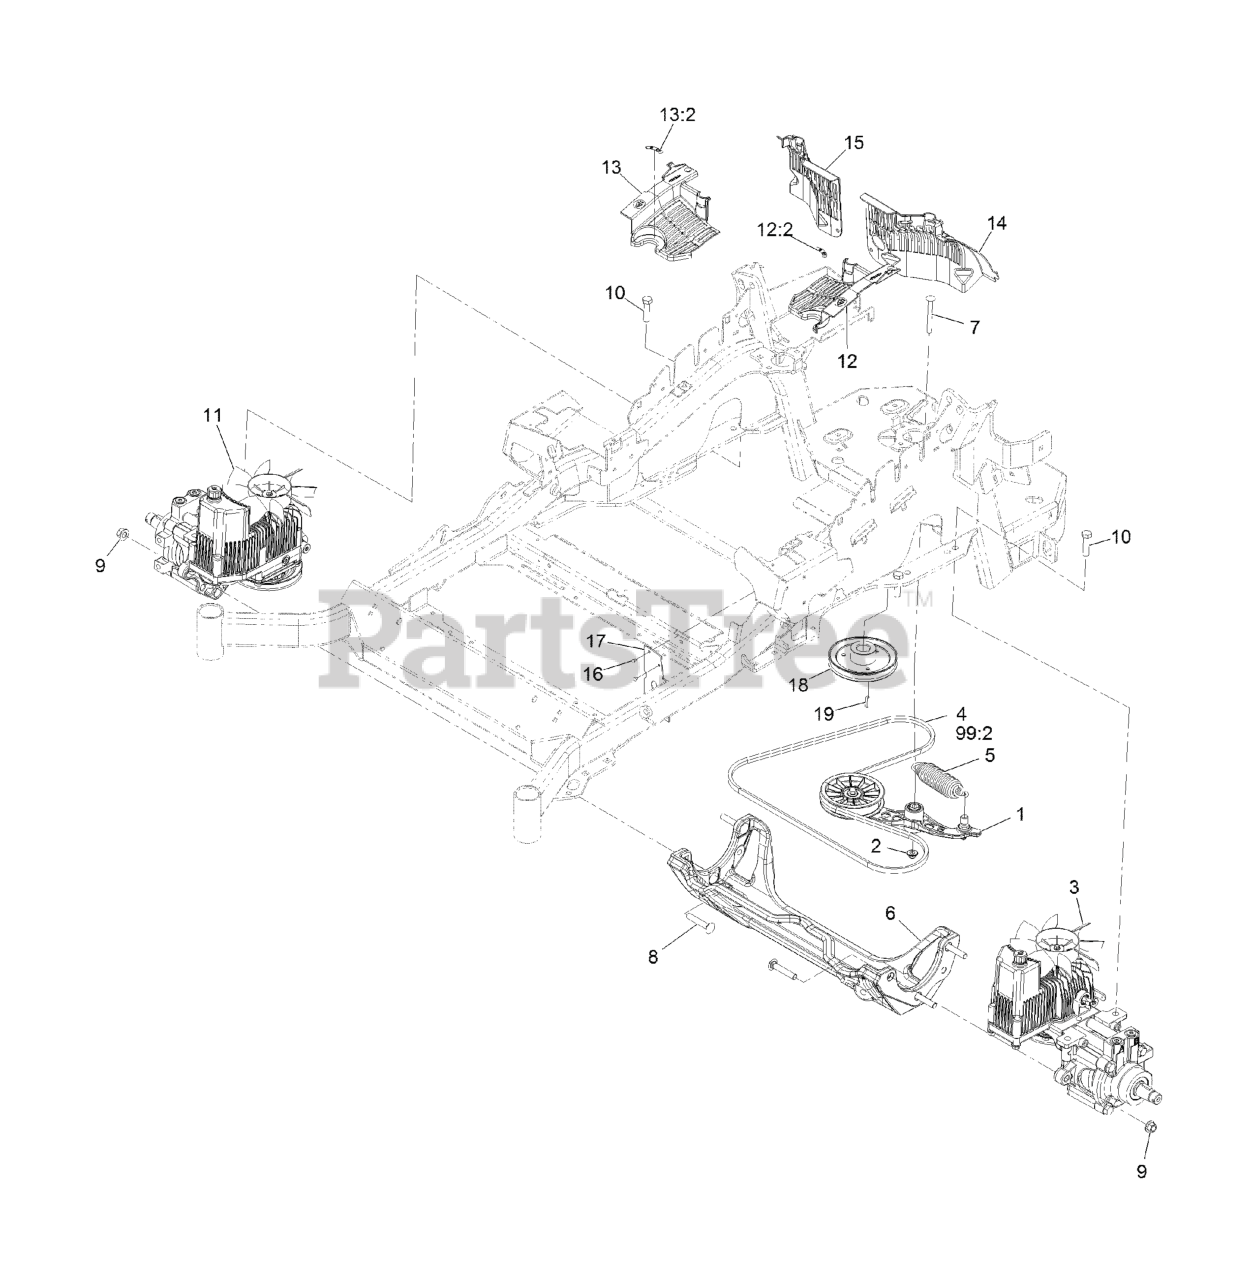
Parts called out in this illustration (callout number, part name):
1	PUMP IDLER ASM
2	Nut-Nyloc 3/8-16 Flg
3	LH HYDRO ASM (12CC W/ SHO
4	BELT
5	SPRING-EXTENSION
6	CRADLE-HYDRO
7	BOLT-SHOULDER, CARRIAGE 3/8-16 X 3 1/2
8	SCREW-CARR
9	Nut-Lock 1/2-13
10	SCREW-HH
11	RH HYDRO ASM (12CC W/ SHO
12	LH HYDRO GUARD ASM
12:2	DECAL-OIL, HYDRO
13	RH HYDRO GUARD ASM
13:2	DECAL-OIL, HYDRO
14	GUARD-HYDRO, REAR (LH)
15	GUARD-HYDRO, REAR (RH)
16	RIVET-POP
17	DEFLECTOR-AIR FLOW
18	SHEAVE
99:2	BELT
